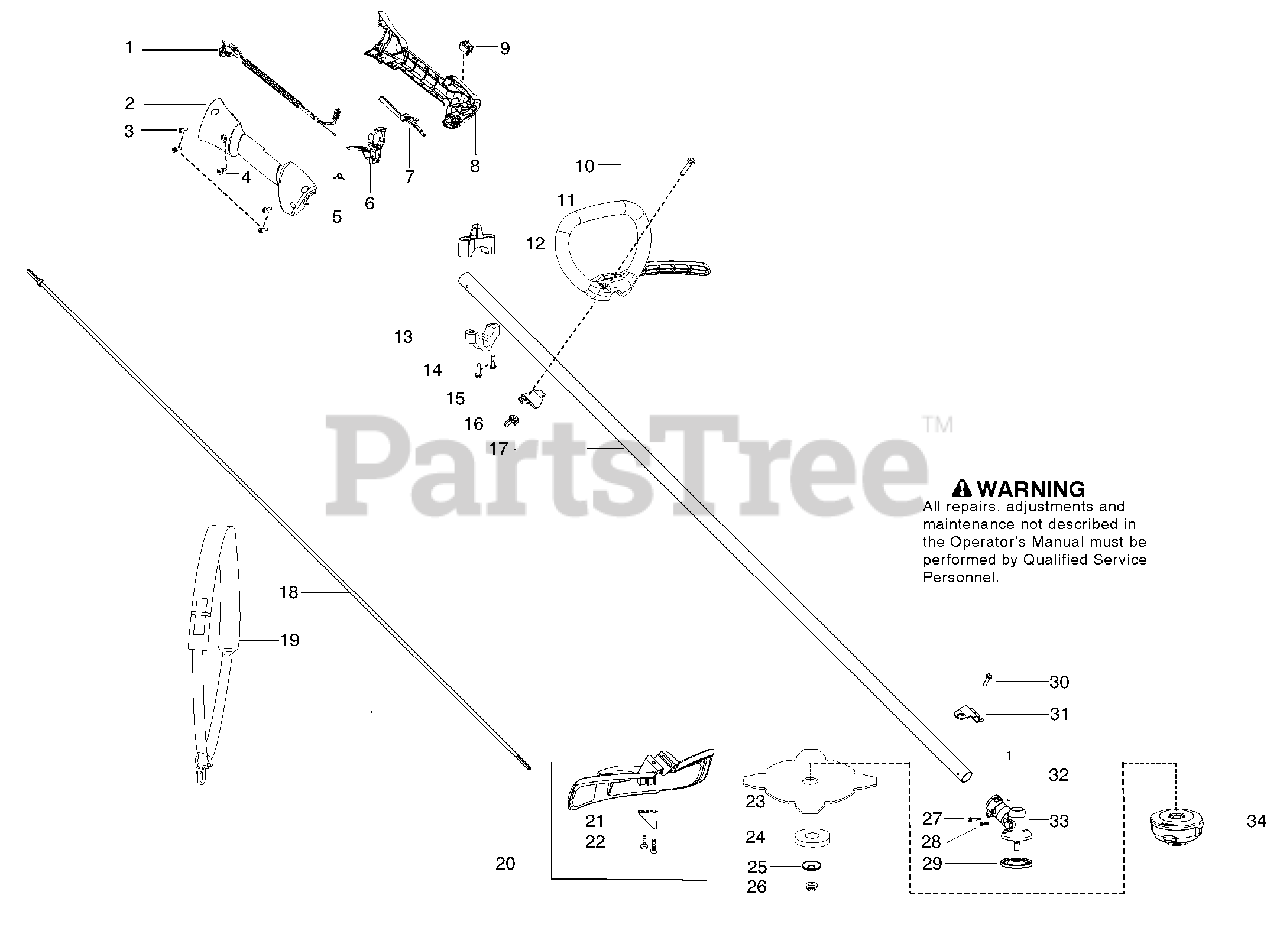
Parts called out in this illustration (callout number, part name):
1	Assy-Cable/Wire Harness
2	Housing-Throttle - RH
3	Screw
4	Screw
5	Spring-Trigger
6	Trigger
7	Lockout-Throttle
8	Housing-Thottle - LH
9	Kit-Switch
11	Assy-Handle/J-Bar
12	Clamp-Harness (upper)
13	Clamp-Harness (lower)
15	Clamp - Handle
16	Wingnut
17	Kit-Driveshaft
19	Harness-w/o warning
20	Kit-Shield
21	Limiter - Line
23	Blade - Grass
24	Cup - Support
25	Support - Flange
26	Locknut - Blade
29	Driver Disc
31	Bracket - Shield
32	Pin - Locking
33	Assy - Gearbox
34	Assy-T25 Cutting Head
